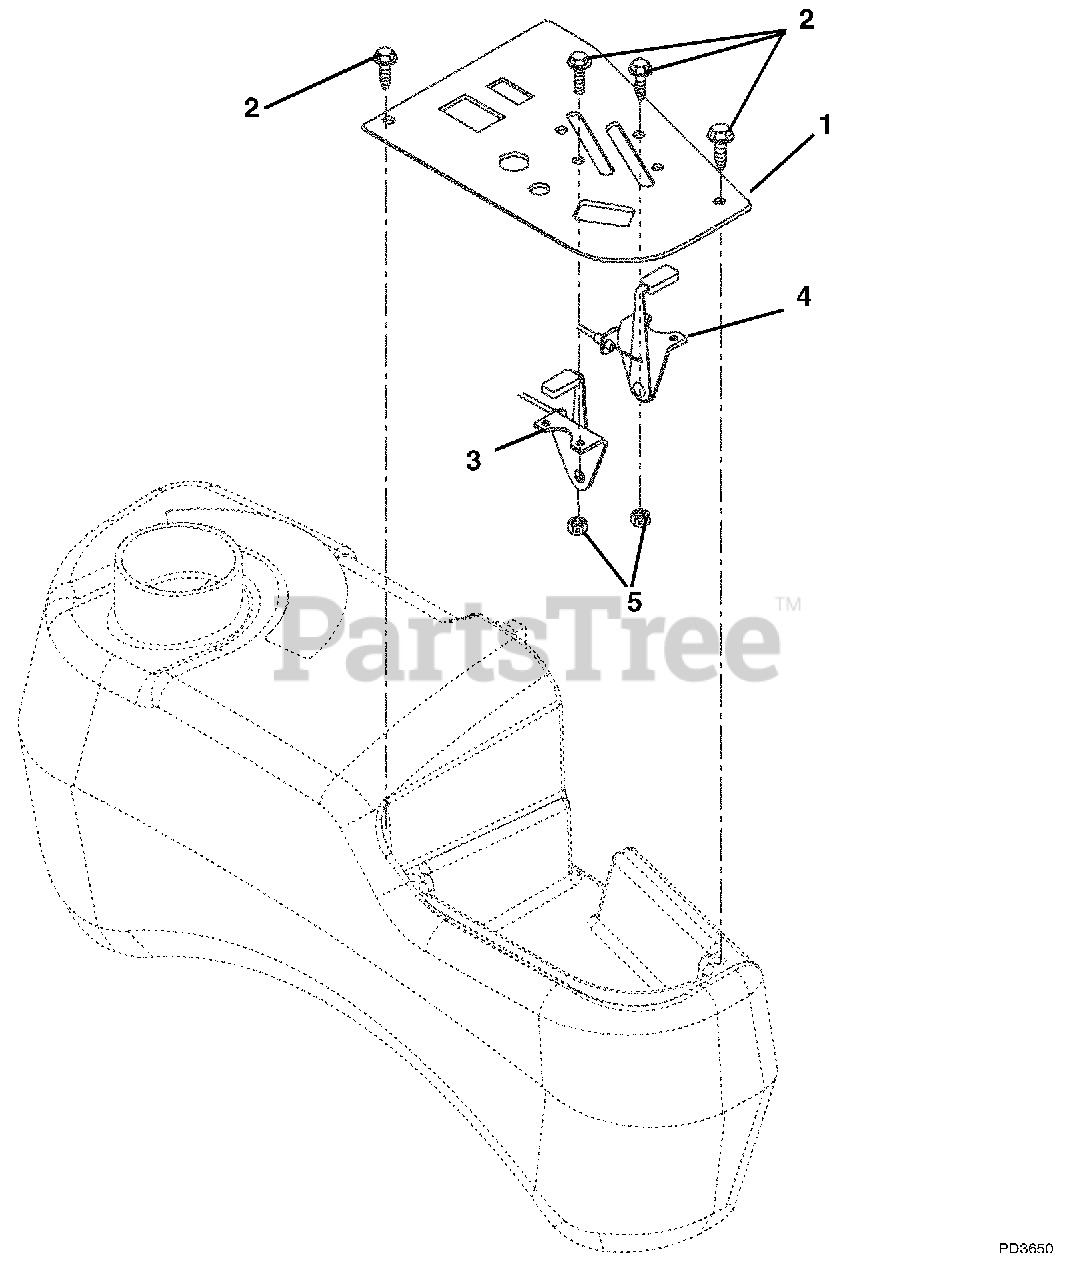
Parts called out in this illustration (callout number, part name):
1	Panel-Control
2	Screw-Machine 10-24 x .50 Hex Washer Head
3	Cable, Throttle
4	Cable, Choke, Kawasaki (042, 043, 044, 051, 310, 311)
4	Cable, Choke, Kohler (054, 055)
5	Nut-Locking-Nylon 10-24 With Insert
